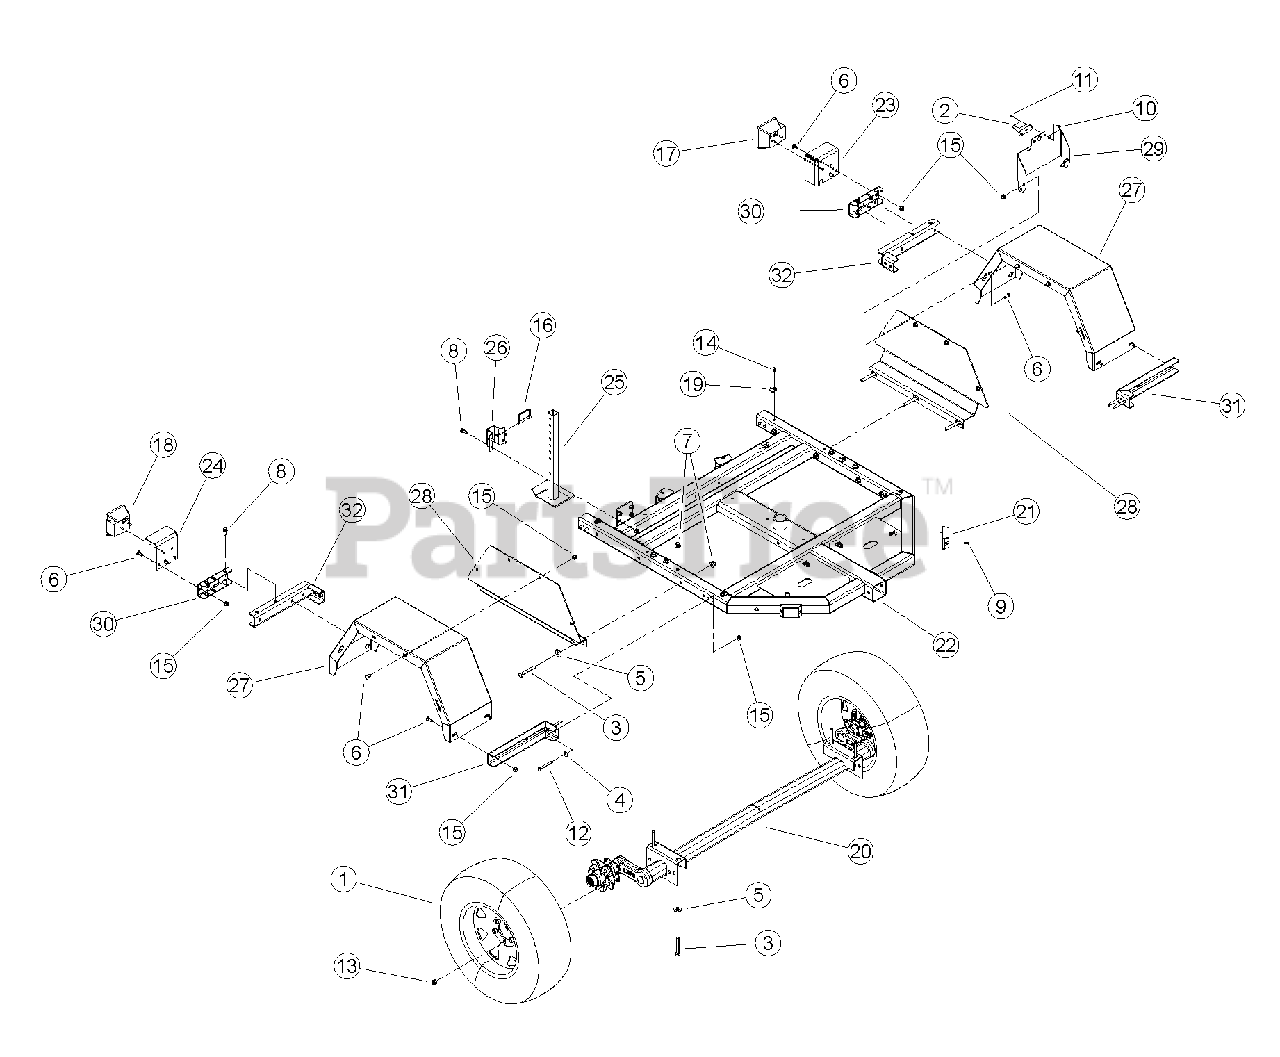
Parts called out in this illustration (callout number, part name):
1	ASSEMBLY, 15 INCH TIRE + WHEEL
2	LIGHT, LICENSE PLATE
3	BOLT, 1/2 X 3-1/2" GR5 HEXHD ZP
4	WASHER, 3/8" FLAT ZP
5	WASHER, 1/2" FLAT ZP
6	BOLT, 3/8 X 1" GR5 CRG NC ZP
7	NUT, 1/2-13 NYLOCK FLANGE
8	BOLT, 3/8 X 1 FLANGE NC
9	SCREW, #10 X 3/4 HEX TAP SC
10	NUT, 10/24 NYLOCK TYPE NM ZP
11	SCREW, MCH 10-24 X 1/2" PAN HD PH ZP
12	BOLT, 3/8 X 3-1/4 HEX HD GR5 ZP
13	NUT, 1/2-20 WHEEL
14	RIVET, AL BLIND 1/4 X 3/4 DOME HEAD
15	NUT, 3/8-16 NYLOCK FLANGE
16	PIN, 3/8 X 2-3/4" SNAP
17	LIGHT, LH TAIL
18	LIGHT, RH TAIL
19	CLAMP, CABLE MOUNT
20	AXLE, TORSION SUSPENSION
21	LIGHT, AMBER MARKER
22	WELDMENT, 8" CHIPPER TRAILER
23	BRACKET, LH TAIL LIGHT
24	BRACKET, RH TAIL LIGHT
25	WELDMENT, REAR STABILIZER
26	GUIDE, TRAILER SUPPORT
27	FENDER, CHIPPER
28	BRACKET, FENDER
29	BRACKET, LICENSE PLATE
30	BRACKET, TAIL LIGHT
31	ANGLE, FENDER GUSSET
32	WELDMENT, FENDER GUSSET
